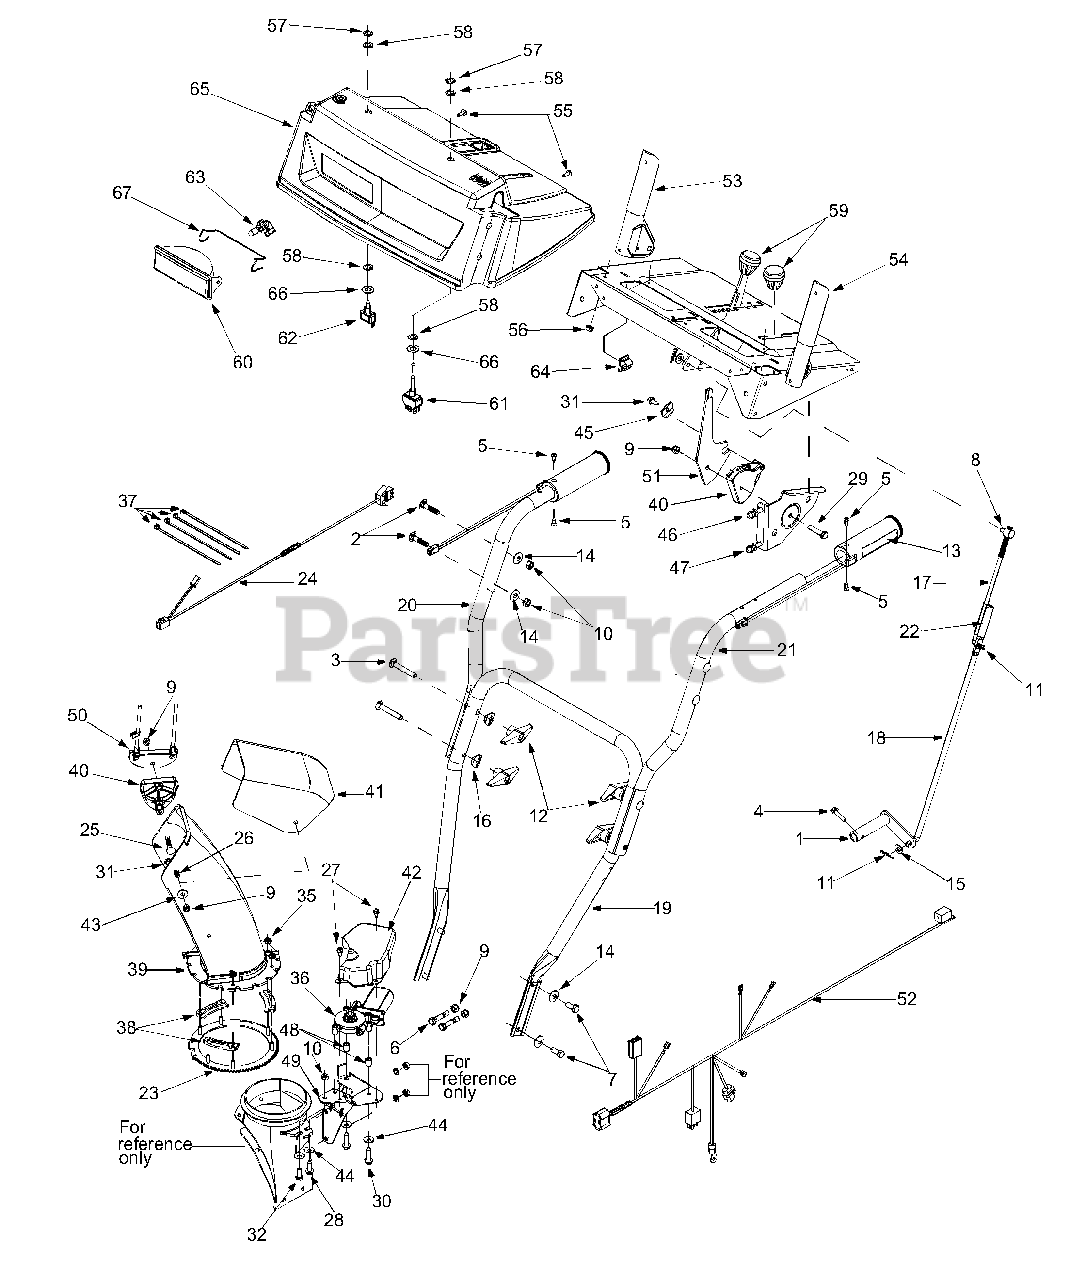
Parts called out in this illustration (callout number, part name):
2	Carriage Bolt 5/16-18 x 1.5"
3	Carriage Bolt 5/16-18 x 2.25"
4	TT Screw 1/4-20 x 1"
5	Oval C-Sk. Screw AB #10-16 x 0.625"
6	Shear Bolt 5/16-18 x 1.5"
7	Hex Screw 5/16-18 x .75"
8	Ferrule
9	Hex Lock Nut 5/16-18
10	Hex Nut 5/16-18
11	Cotter Pin
12	Handle Knob
13	Heated Grip
14	Bell Washer
15	Flat Washer
16	Saddle Washer
17	Shift Rod: Upper
18	Shift Rod: Lower
23	Gear Assembly: Ring
24	Electric Harness: Lower
25	Carriage Bolt: 5/16-18 x 1.5"
26	Carriage Bolt: 5.16-18 x .750"
27	TT Screw: 1/4-20 x 0.5"
28	TT Screw: 5/16-18 x 1"
29	Hex Screw: 5/16-18 x 1.5"
30	TT Screw: 5/16-18 x 1.25"
31	Hex Screw AB: 1/4-14 x 0.625"
32	Hex Screw: 5/16-18 x .75"
35	Hex Flange Lock Nut
36	Electric Motor: Chute Crank
37	Cable Tie
38	Chute Flange Keeper
39	Lower Chute
40	Cable Guide: Chute Tilt
41	Upper Chute
42	Motor Cover: Chute Rotation
43	5/16 Washer
44	Bell Washer
45	Special Washer
46	Control Cable
47	Control Cable
48	Spacer
52	Harness Assembly: Upper
53	Handle Asm. RH: Engagement
54	Handle Asm. LH: Engagement
55	Special Hex Screw
56	Hex Sems Nut: 1/4-20
57	Hex Nut
58	Lock Ring: Toggle Switch
59	Shift Knob
60	Lamp Housing
61	Toggle Switch: Double Throw
62	Toggle Switch: Single Throw
63	Halogen Lamp: 50W, 12V
64	Mounting Clamp
65	Handle Panel
66	Flat Washer
67	Headlight Retainer
